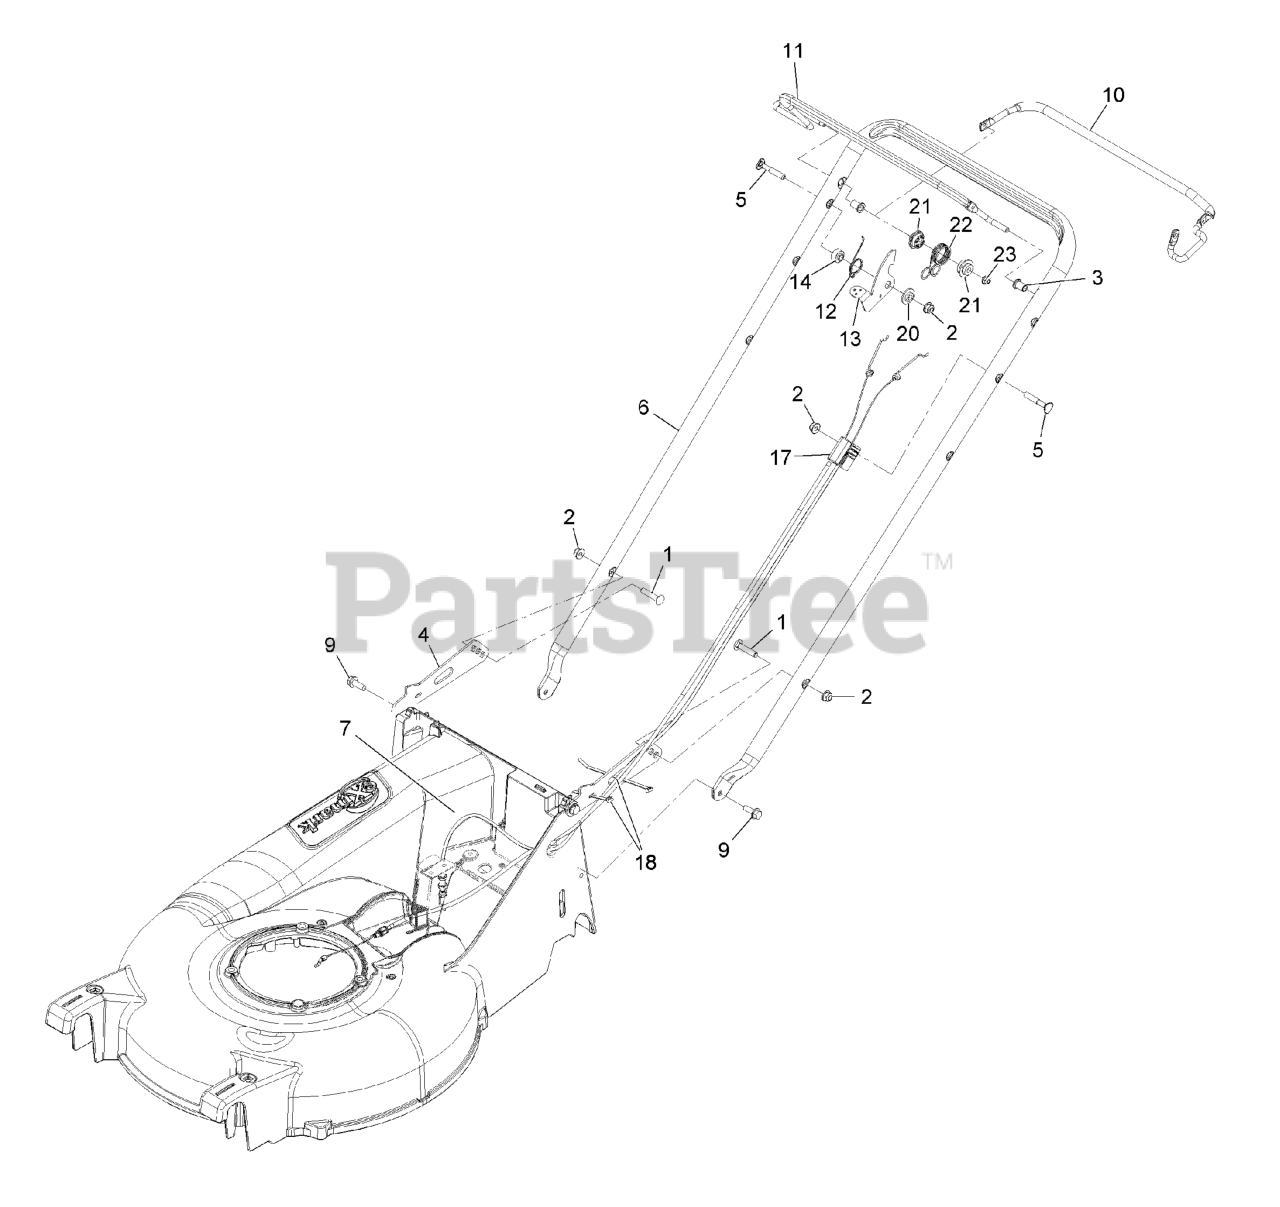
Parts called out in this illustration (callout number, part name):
1	BOLT-CARR
2	NUT-HF, NI
3	BUSHING-HANDLEBAR
4	BRACKET,HANDLEBAR
6	HANDLEBAR-P21
7	CABLE, DRIVE EC21
9	SCREW-TAPTITE
10	BAIL-DRIVE COATED
12	SPRING-LEVER, BBC
13	LEVER-BBC
14	BUSHING-STEPPED
17	CABLE-BBC
18	TIE-CABLE
20	WASHER-STEPPED
21	BUSHING-SPRING, PIVOT
22	SPRING,BBC RETURN
